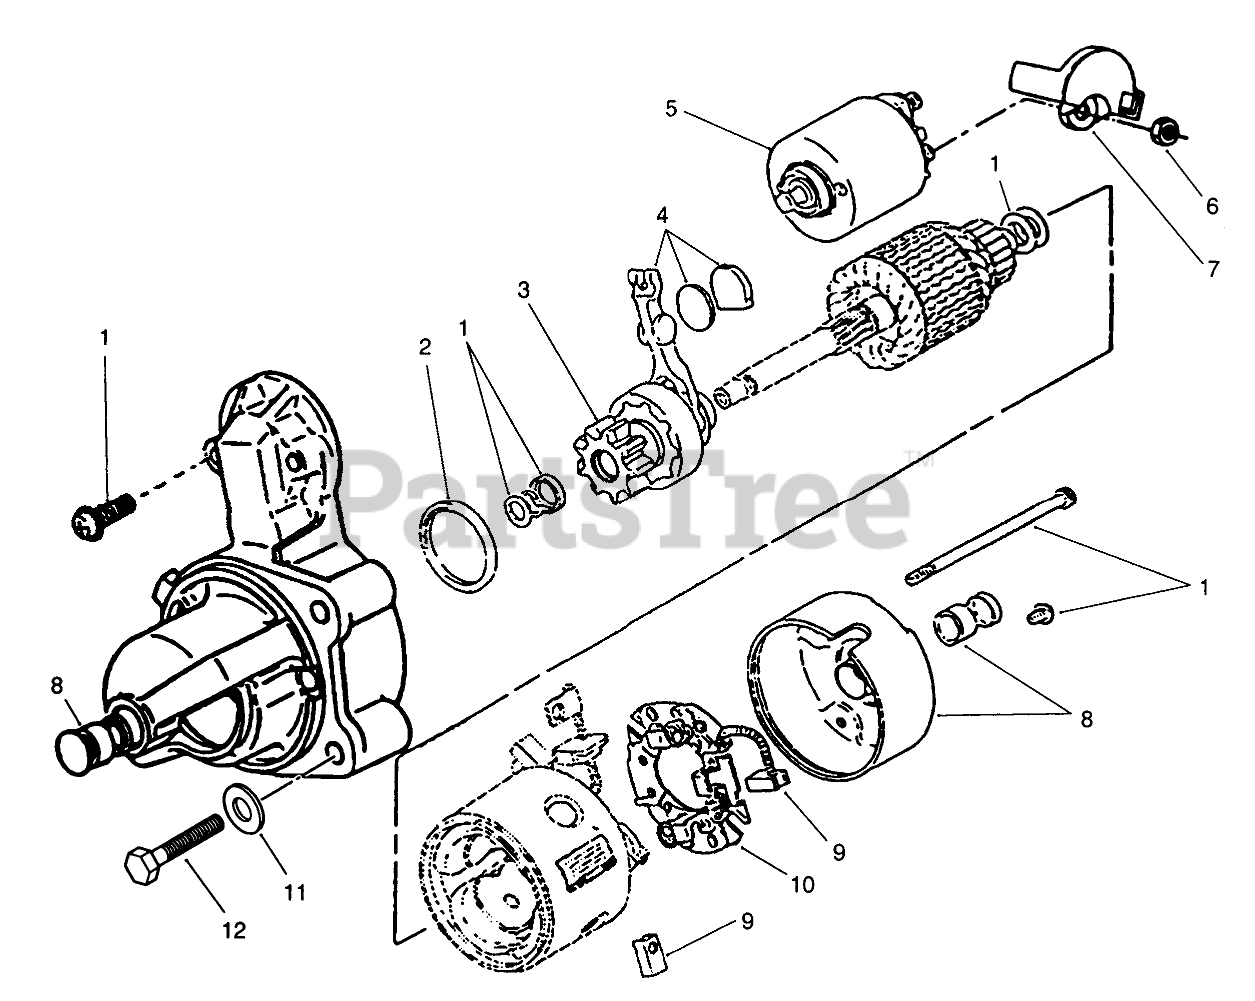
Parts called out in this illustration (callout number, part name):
1	Kit-Hardware, Starter #191-1808-04 (Incl. Solenoid Screws, Brush Holder Screws, Thru Bolts, Armature, Shims, Pinion Stop Collar, & Pinion Retaining Rings)
2	Dust Seal
3	CLUTCH STARTER ASSEMBLY
4	LEVER
5	STARTER SOLENOID KIT
6	Nut-Hex.
7	Cap-Starter Solenoid
8	Kit-Bushing, Starter #191-1808-04 (Incl. Rear Cap, Front & Rear Bushings)
9	BRUSH KIT
10	Brush Mounting Kit
11	Washer
12	Screw-Hex Hd
13	KIT-MTG BRKT
14	WASHER
